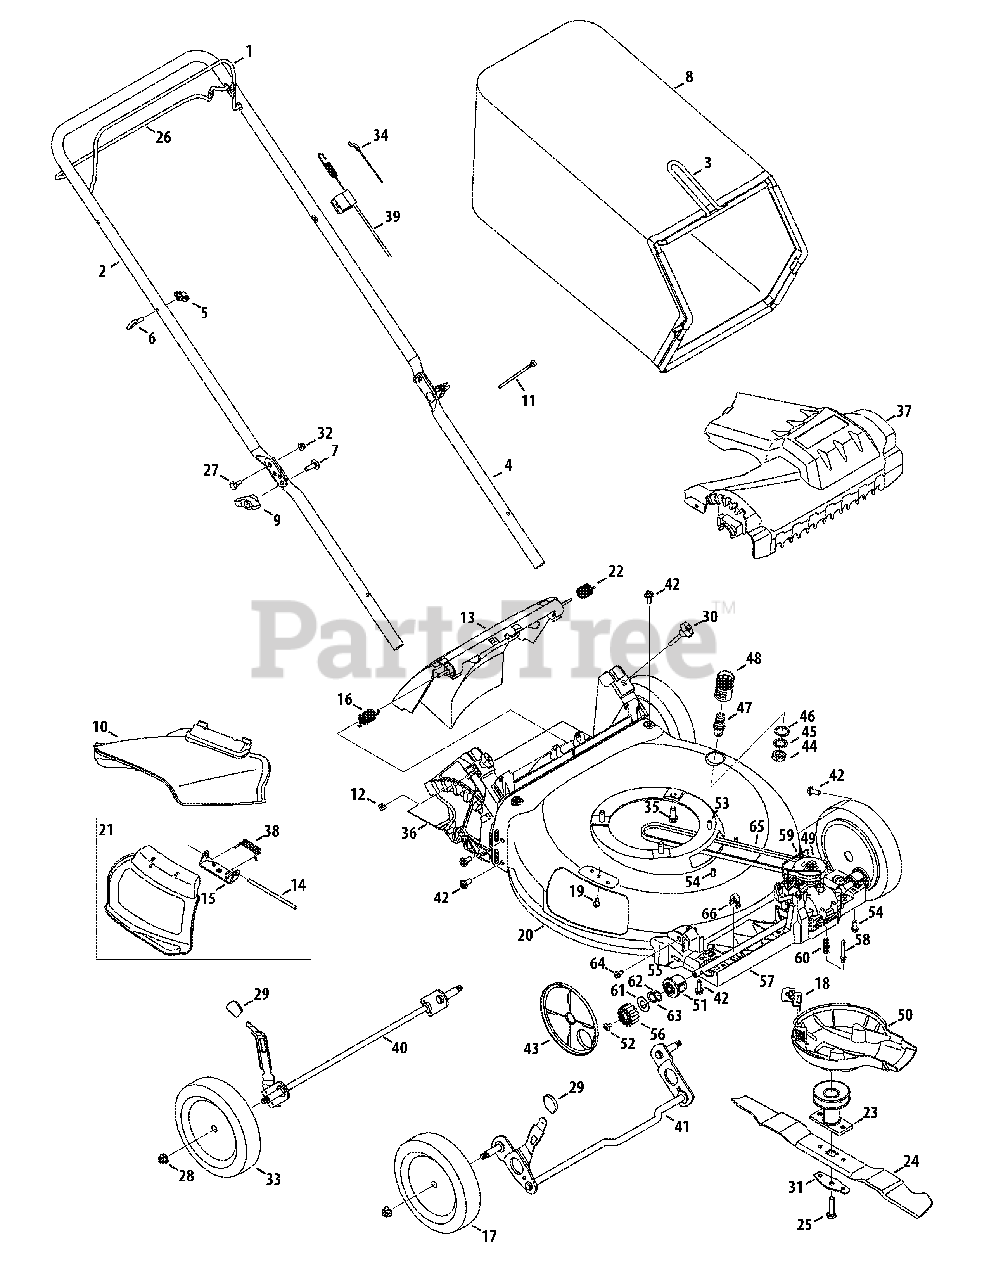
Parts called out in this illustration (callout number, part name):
1	Blade Control
2	Upper Handle
3	Grass Catcher Frame
4	Lower Handle
6	Rope Guide
7	Carriage Screw, 5/16-18
8	Grass Bag
10	Side Chute
11	Cable Tie
12	Nut, Sq., 1/4-20
13	Rear Discharge Door & Baffle Assembly-Generic
13	Rear Discharge Door & Baffle Assembly-Lowes
14	Hinge Pin
15	Chute Deflector Bracket
16	Torsion Spring - RH
17	Front Wheel
18	Engine Baffle Bracket
19	Screw, 1/4-20 x .500
20	Deck, 21"
21	Hinged Mulch Plug Assembly
22	Torsion Spring - LH
23	Blade Adapter Assembly
24	Mulching Blade
25	Screw, 3/8-24 x 1.50
26	Drive Control
27	Sldr. Screw, .375 x .126 x 1/4-20
28	Flange Lock Nut, 3/8-16
29	Adjustment Lever Knob
30	Wing Nut
31	Blade Bell Support
32	Nut, Flange Lock, 1/4-20
33	Rear Wheel
34	Control Cable
35	TT Sems Screw, 3/8-16 x 1.0
36	Trail Shield
37	Front Cover
38	Torsion Spring
39	Drive Cable
40	Rear Axle Assembly
41	Front Axle Assembly
42	Screw, 5/16-14 x .750
43	Wheel Dust Cover
44	Nut, Hex
45	Washer, Lock, 5/8"
46	Wash., Flat, .865 x 1.145 x .030
47	Water Nozzle
48	Water Nozzle Adapter
49	Transmission Assembly
50	Engine Baffle
51	Bearing Assembly
52	Screw, 1/4-20 x .390
53	Screw, 1/4-20 x .500
54	Screw, 1/4-15 x .750
55	Dowel Pin
56	Spur Gear, 14T - RH
56	Spur Gear, 14T - LH
58	Spring Body
59	Transmission Wire
60	Compression Spring
61	Wash., Flat, .508 x 1.00 x .020
62	Wash., Flat, .504 x .700 x .010
63	Wash., Saddle, .505 x .740 x .125
64	Screw., Sldr., 1/4-20 x .70
66	Front Axle Clip
